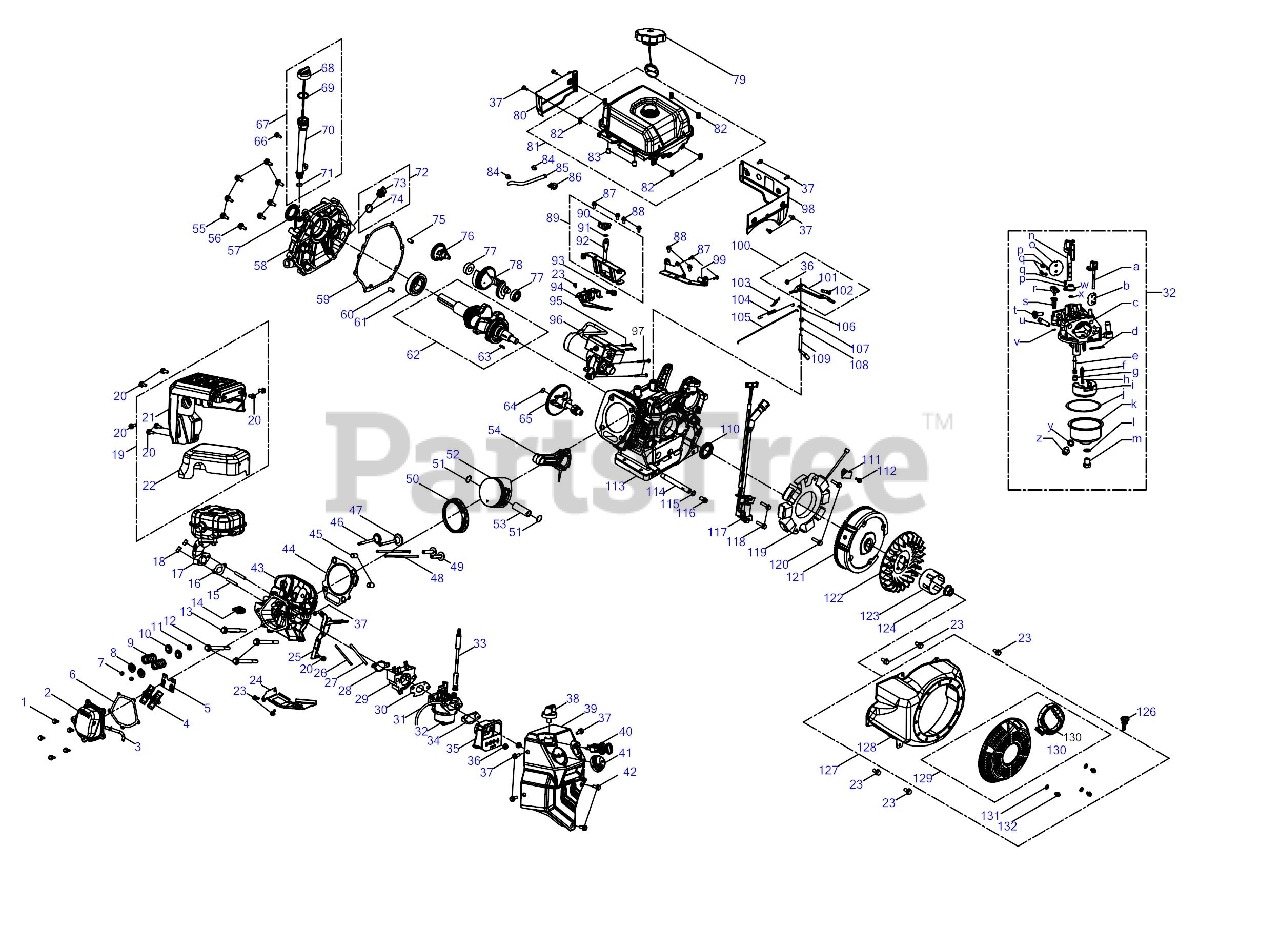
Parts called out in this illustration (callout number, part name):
1	Bolt, M6?16
2	Valve Cover
3	Breather Hose
4	Rocker Arm Assembly
5	Rocker Arm Base
6	Gasket, Valve Cover
7	Valve Adjust Cap, Exhaust
8	Valve Spring Seat
9	Valve Spring
10	Valve Spring Seat
11	Intake Valve Seal
12	Bolt, M10?1.25?87
13	Bolt, M10?1.25?65
14	Spark Plug
15	Stud, M8?48.5
16	Gasket, Muffler
17	Muffler
19	Muffler Guard
20	Bolt, M6?10
21	Muffler Shroud
22	Muffler Inner Shield
23	Bolt, M6?12
25	Snow Guard
26	Stud, M6-8?108
27	Stud, M6-8?126
28	Gasket, Carburetor Insulator
29	Insulator
30	Carburetor Gasket
31	Fuel Hose, 3.2?6.5?170
32	Carburetor
33	Choke Linkage
34	Gasket, Air Filter
35	Heater Box
37	Bolt, M6?14
38	Choke Lever
39	Control Panel
40	Stop Switch
42	Bolt, M6?20
43	Cylinder Head Assembly
44	Gasket, Cylinder Head
45	Pin, 12?20
46	Exhaust Valve
47	Intake Vavle
48	Push Rod
49	Tappet
50	Piston Ring Set
51	Circlip
53	Piston Pin
54	Connecting Rod Assembly
55	Bolt, M8?38
56	Bolt, M8?45
57	Oil Seal, 35?52?7
58	Crankcase Cover
59	Gasket, Crankcase
61	Bearing, 6207
62	Crankshaft
63	Woodruff Key
64	Washer, 16.2?0.3?24
65	Camshaft
66	Bolt, M6?18
67	Dipstick
69	O-Ring, 21?2.77
70	Dipstick Seat
71	O-Ring, 13.5?2.5
72	Oil Plug
73	Oil Plug
74	O-Ring, 16?3
75	Pin, 7?14
76	Governor Gear
77	Bearing, 6202
78	Balance Shaft
80	Decorative Sheet, Right
82	Fuel Tank Mount Thread Tab
83	Bush, 10?14?14
84	Clamp
85	Fuel Hose, 6.3?12.5?255
86	Clip
87	Bolt, M8?28
88	Bolt, M8?14
89	Front Bracket, Fuel Tank
90	Rubber Grommet
91	Retaining Ring, 10
92	Front Bracket, Fuel Tank
93	Throttle Lever Knob
94	Governor Gear Bracket Assembly
95	Screw, M4?48
96	Electric Starter
97	Bolt, M8?55
98	Decorative Sheet, Left
99	Fuel Tank Base
100	Governor Lever
101	Governor Lever
103	Governor Spring
104	Idle Spring
105	Throttle Linkage
106	Cotter Pin
107	Oil Seal, 8?14?4
108	Washer, 8?0.8?20
109	Governor Gear Shaft
110	Oil Seal, 35?52?7
111	Wire Board
112	Bolt, M6?8
114	Oil Drain Pipe
115	Washer, 10?1.5?16
116	Earth Bolt
117	Ignition Module
118	Bolt, M6?28
119	Charging Coil
120	Bolt, M6?30
122	Cooling Fan
123	Starter Cup
124	Nut, M16?1.5
125	Tape, L=150mm
126	Stop Switch Key
127	Recoil Starter
128	Blower Housing
129	Recoil Starter
130	Starter Handle
131	Washer, 6
132	Bolt, M6?10
